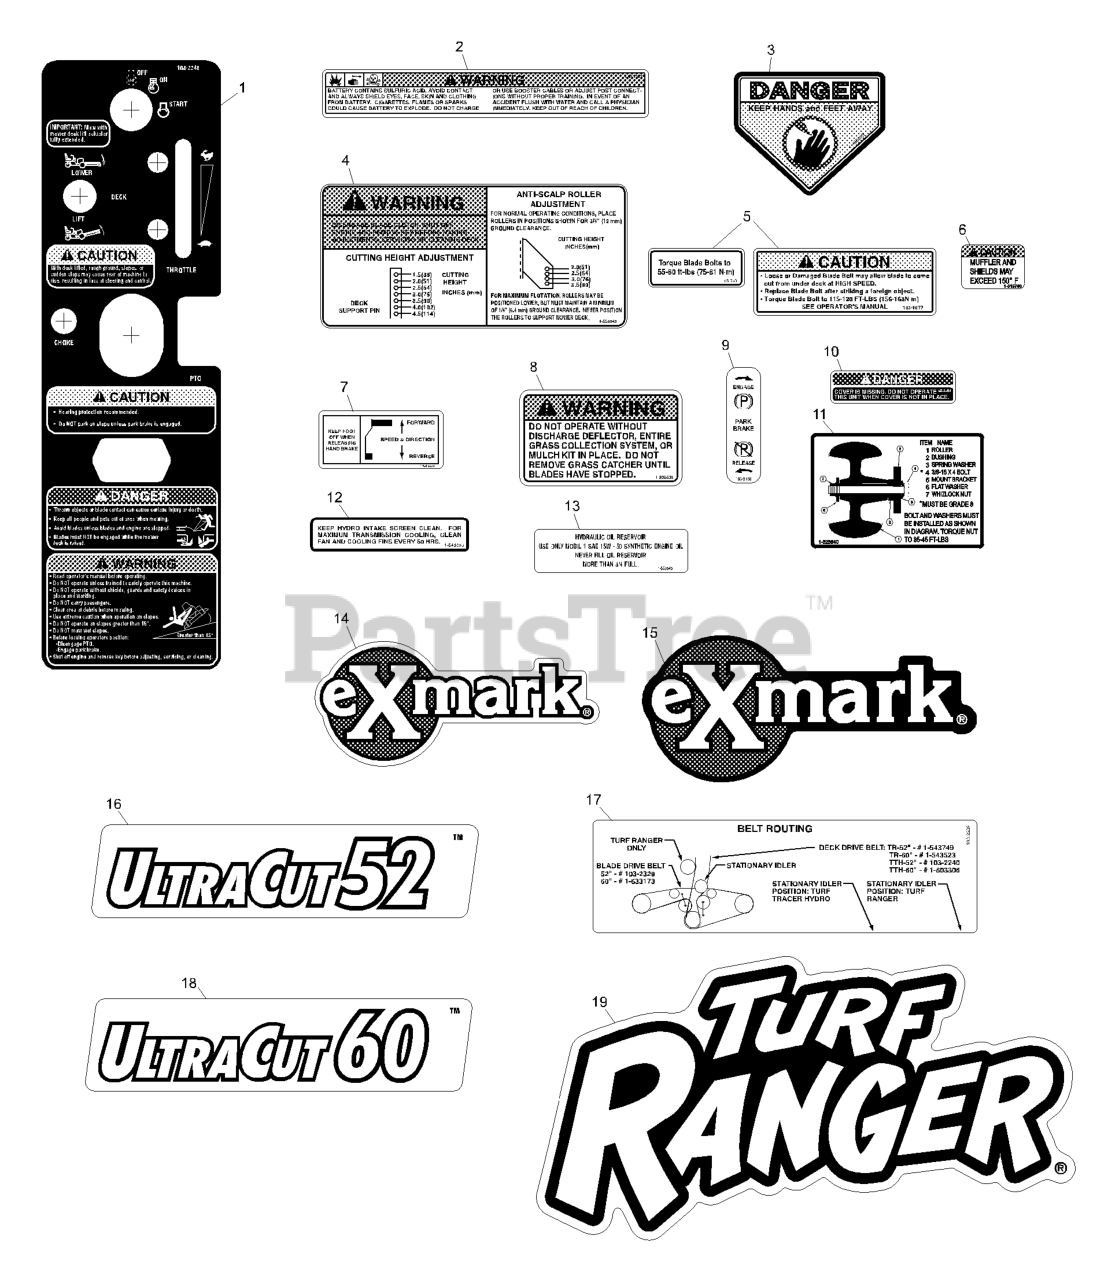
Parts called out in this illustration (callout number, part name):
1	DECAL, CONSOLE
2	DECAL-BATTERY
3	DECAL-DANGER
4	DECAL,ANTI SCALP
5	DECAL,BOLT TORQUE
7	DECAL,FOOT PEDAL
8	DECAL-WARNING, DISCHARGE
9	DECAL,PARKING BRAKE
10	DECAL-COVER, MISSING
11	DECAL,ROLLER MOUNTING
12	DECAL,INTAKE
13	DECAL,HYDRAULIC TANK
14	DECAL,EXMARK LOGO
15	DECAL,EXMARK LOGO
16	DECAL,ULTRACUT 52
17	DECAL,BELT ROUTING
18	DECAL,ULTRACUT 60
